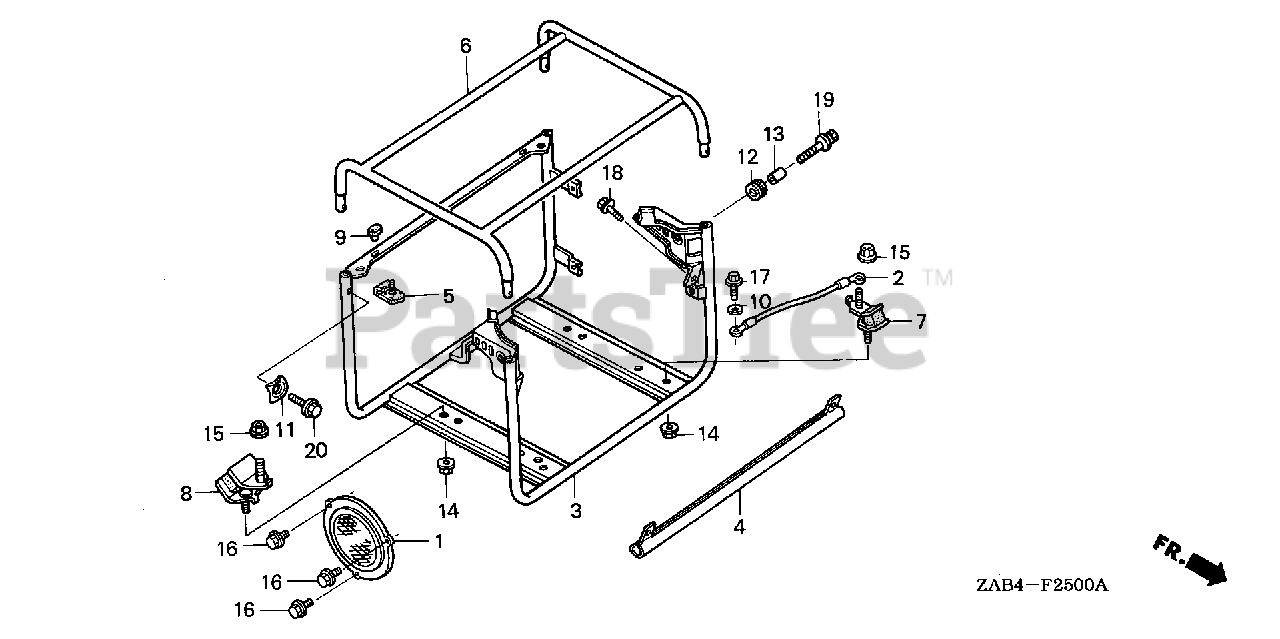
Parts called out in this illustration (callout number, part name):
1	PROTECTOR, FAN COVER *NH1* (BLACK)
2	CABLE, GROUND
3	FRAME (LOWER) *NH105* (MAT BLACK)
4	CHANNEL, FR. *NH105* (MAT BLACK)
5	RUBBER, TANK MOUNTING
6	FRAME (UPPER) *NH105* (MAT BLACK)
7	RUBBER (LOWER)
8	RUBBER (LOWER)
9	STOPPER, DISCHARGE GUARD
10	WASHER, LOCK (6MM)
11	WASHER, FRAME JOINT
12	RUBBER, CONTROL BOX
13	COLLAR, CONTROL BOX
14	NUT, FLANGE (8MM)
15	NUT, FLANGE (10MM)
16	BOLT, FLANGE (6X10)
16	BOLT, FLANGE (6X8)
17	BOLT, FLANGE (6X10)
18	BOLT, FLANGE (6X12)
19	BOLT-WASHER (6X20)
20	BOLT, FLANGE (8X16)
